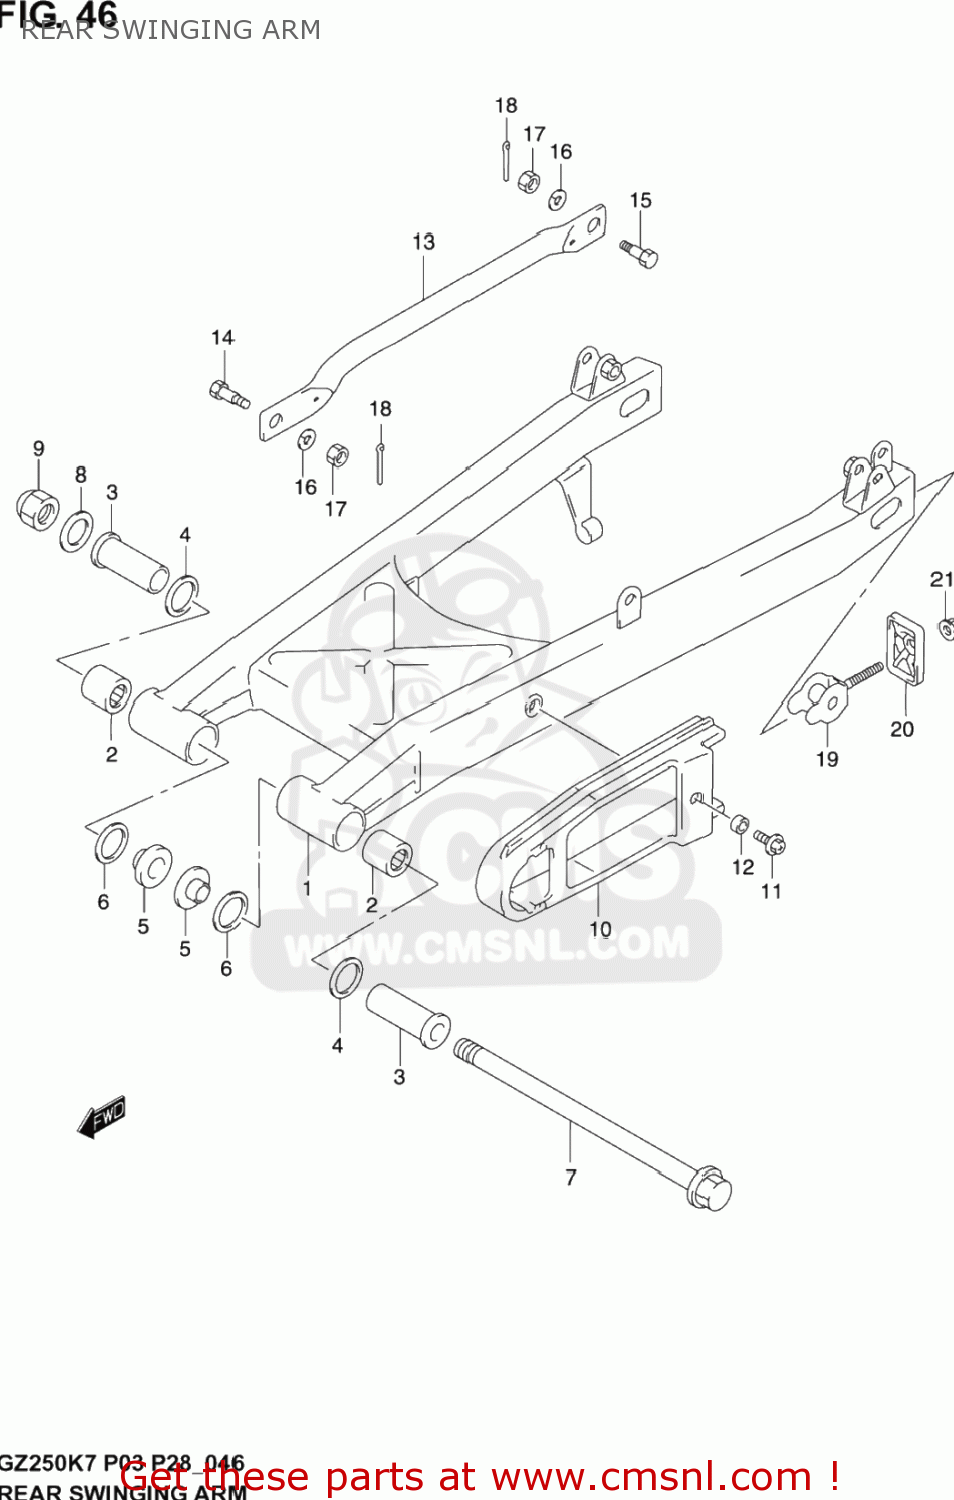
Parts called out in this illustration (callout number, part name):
1	SWINGING ARM ASSY, REAR
2	BEARING(20X27X20)
3	SPACER, PIVOT OUTER
4	SEAL,OIL(20X27X5)
5	SPACER, PIVOT INNER
6	SEAL,OIL(20X27X5)
7	SHAFT,RR SWINGINGARM PIVOT
8	WASHER
9	NUT 14MM
10	BUFFER,CHAIN TOUCH DEFENSE
11	BOLT 6X20,WITH PLAIN WASHER
12	SPACER(6.5X9X3.8)
13	TORQUELINK,RR
14	BOLT(8X22.5)
15	BOLT(8X26.5)
16	WASHER,LOCK
17	NUT
18	PIN 20X20
19	ADJUSTER,CHAIN
20	PLATE,CHAIN ADJUSTER
21	NUT
